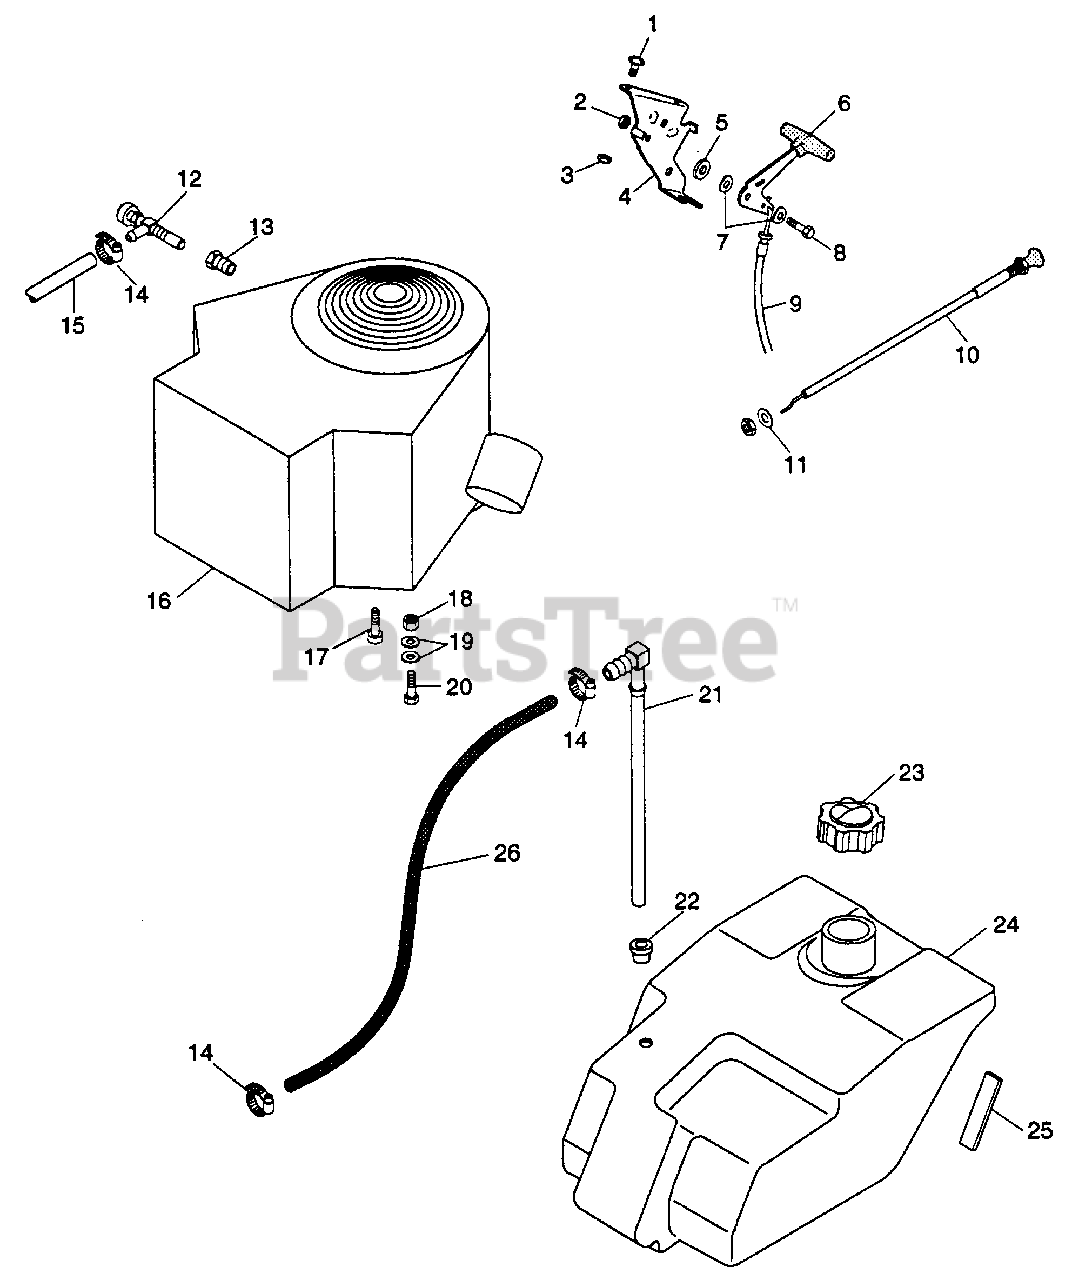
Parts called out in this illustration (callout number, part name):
1	Scr-Mch 10-24 x .625 P/HD
2	Nut-Lk-Ctr .250-28 Typ N
3	Nut-Lk 10-24 Ny Pl
4	Bracket-Throttle Cable
5	Wshr-Fl-Stl .281 x .625 x .065
6	Knob & Lever Ass'y
7	Spring Washer
8	Blt-Hex .25-28 x .63
9	Cable
10	Choke Cable
11	Wshr-Fl-Stl .406 x .812 x .065 Pl
12	Cock, Oil Drain
13	Adapter, Oil Drain
14	Hose Clamp
15	Gas Line Hose 11"
16	Engine 16 HP B & S
17	Blt-Hex M8 x 1.25 x 20mm Pl
18	Nut-Lk-Nyl .312-18 Pl
19	Wshr-Fl-Stl .344 x .688 x .065
20	Blt-Hex .31-18 x 1.75 Gr 5
21	Tank Fitting
22	Bushing
23	Fuel Cap
24	Fuel Tank
25	Pad, Gas Tank
26	Gas Line Hose 53"
